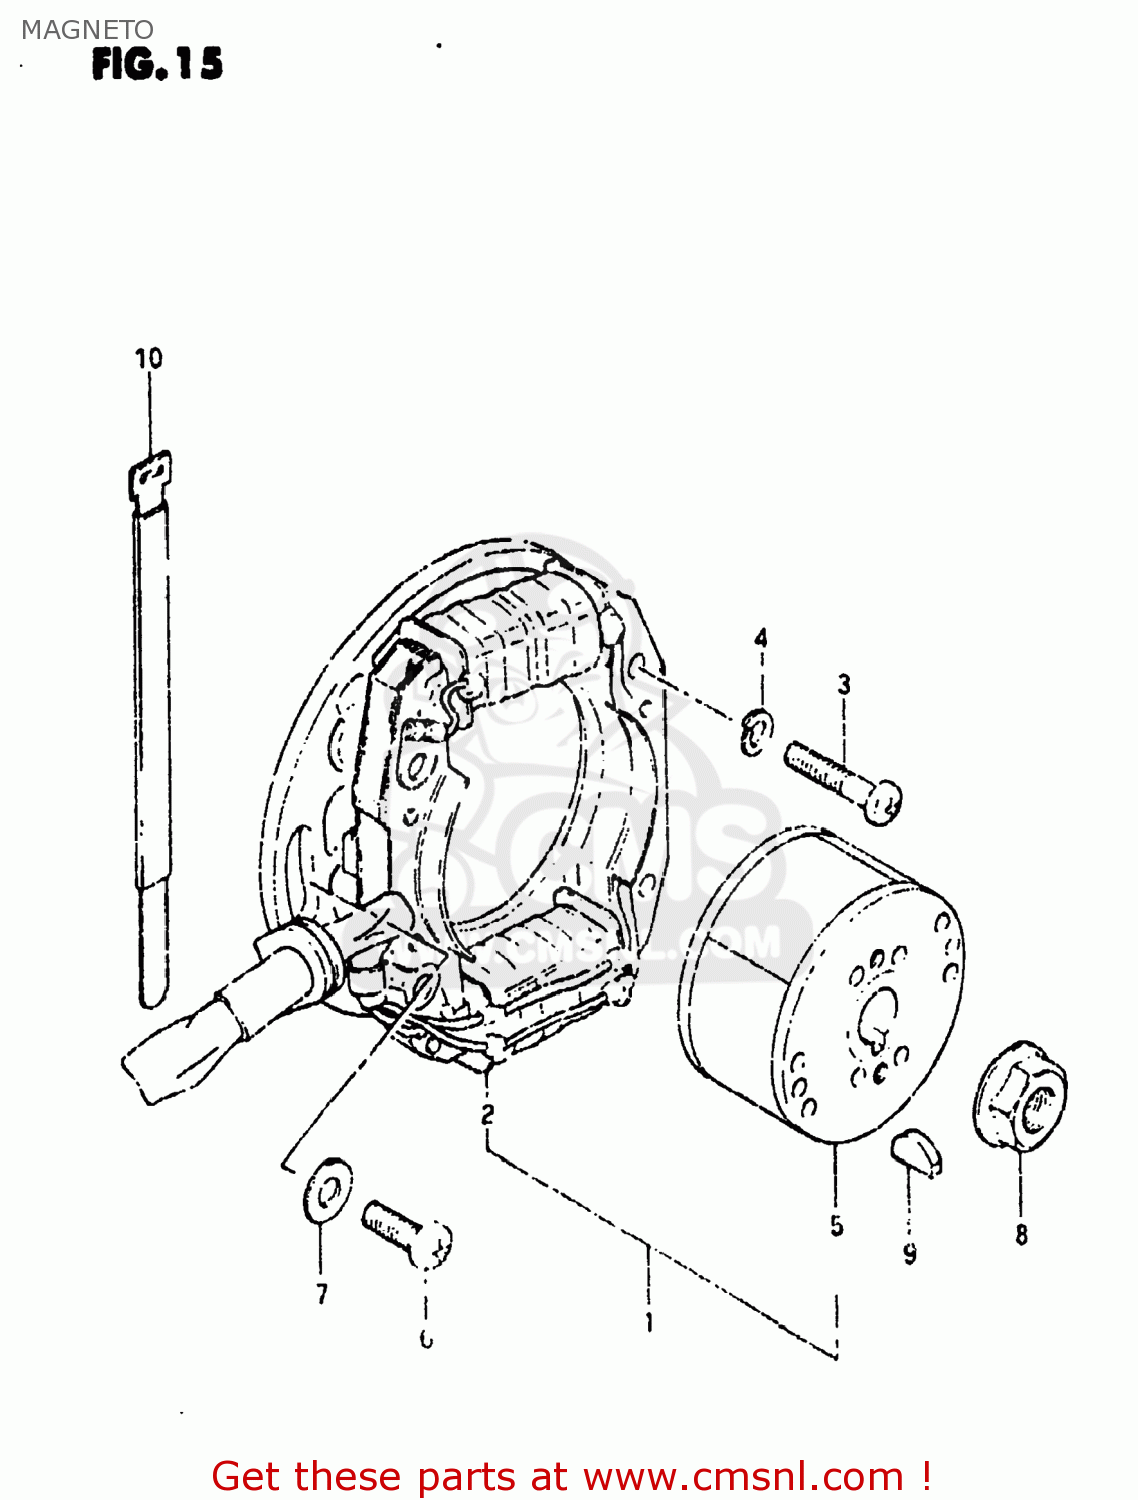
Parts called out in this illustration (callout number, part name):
1	MAGNETO ASSEMBLY
2	STATOR ASSEMBLY
3	SCREW 5X20
4	LOCK WASHER
5	ROTOR ASSEMBLY
6	SCREW
7	WASHER
8	NUT
9	KEY 4MM
10	CLAMP
